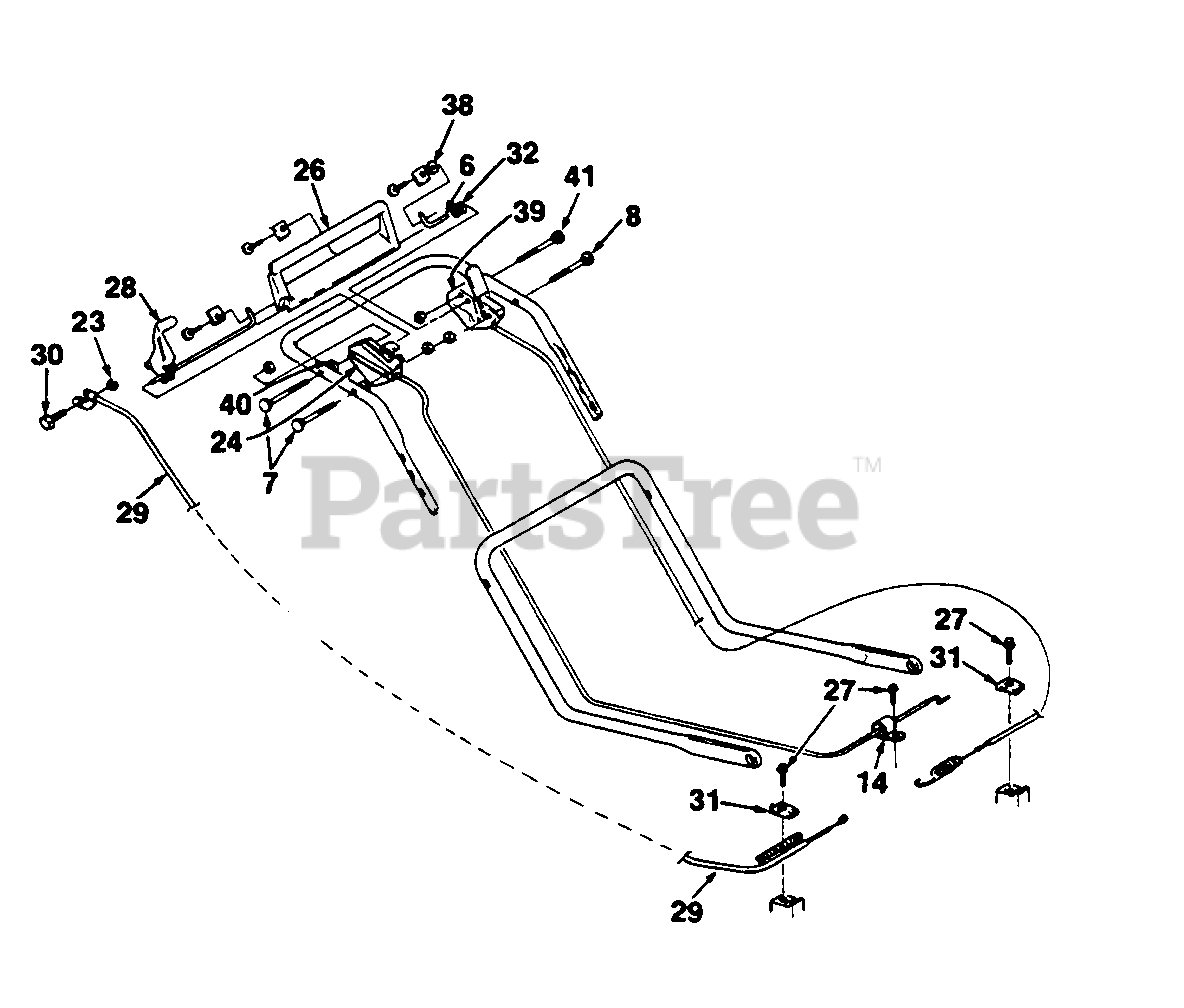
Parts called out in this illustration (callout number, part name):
6	SHAFT - Pivot
7	BOLT- Sq. neck
8	BOLT- Sq. neck
23	NUT-Lock (1/4-20)
24	CONTROL-Throttle
26	BAIL- Brake control
27	SCREW- 1/4-20 x 5/8"
28	TRACTION LEVER ASSY.
29	CONTROL CABLE TBO
30	SCREW - 1/4-20 x 1 1/2"
32	SPRING - Compression
38	Washer, Flat, 7.25 ID x 16 OD
39	CONTROL-BBC
41	BOLT- Sq. neck (1/4-20 x 2 1/8")
